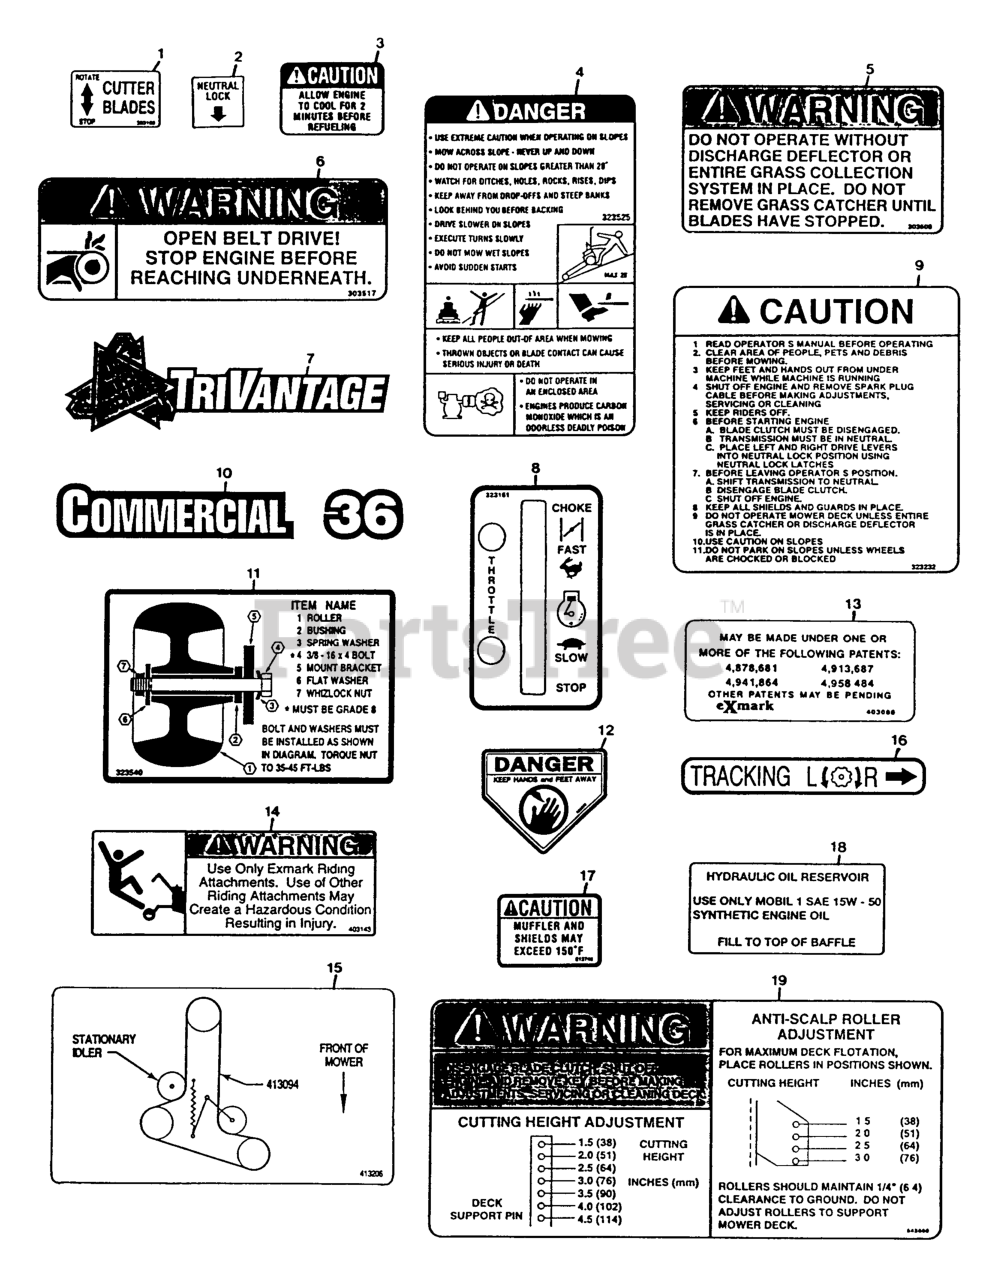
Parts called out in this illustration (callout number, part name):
1	DECAL,CUTTER BLADE
2	DECAL,NEUTRAL LOCK
5	DECAL-WARNING, DISCHARGE
6	DECAL,BELT DRIVE
9	DECAL,INSTRUCTIONAL
10	DECAL,COMMERCIAL 36
11	DECAL,ROLLER MOUNTING
12	DECAL-DANGER
14	DECAL,SULKY WARNING
15	DECAL,BELT ROUTING
16	DECAL,TRACKING ADJUST
18	DECAL,HYD TANK
